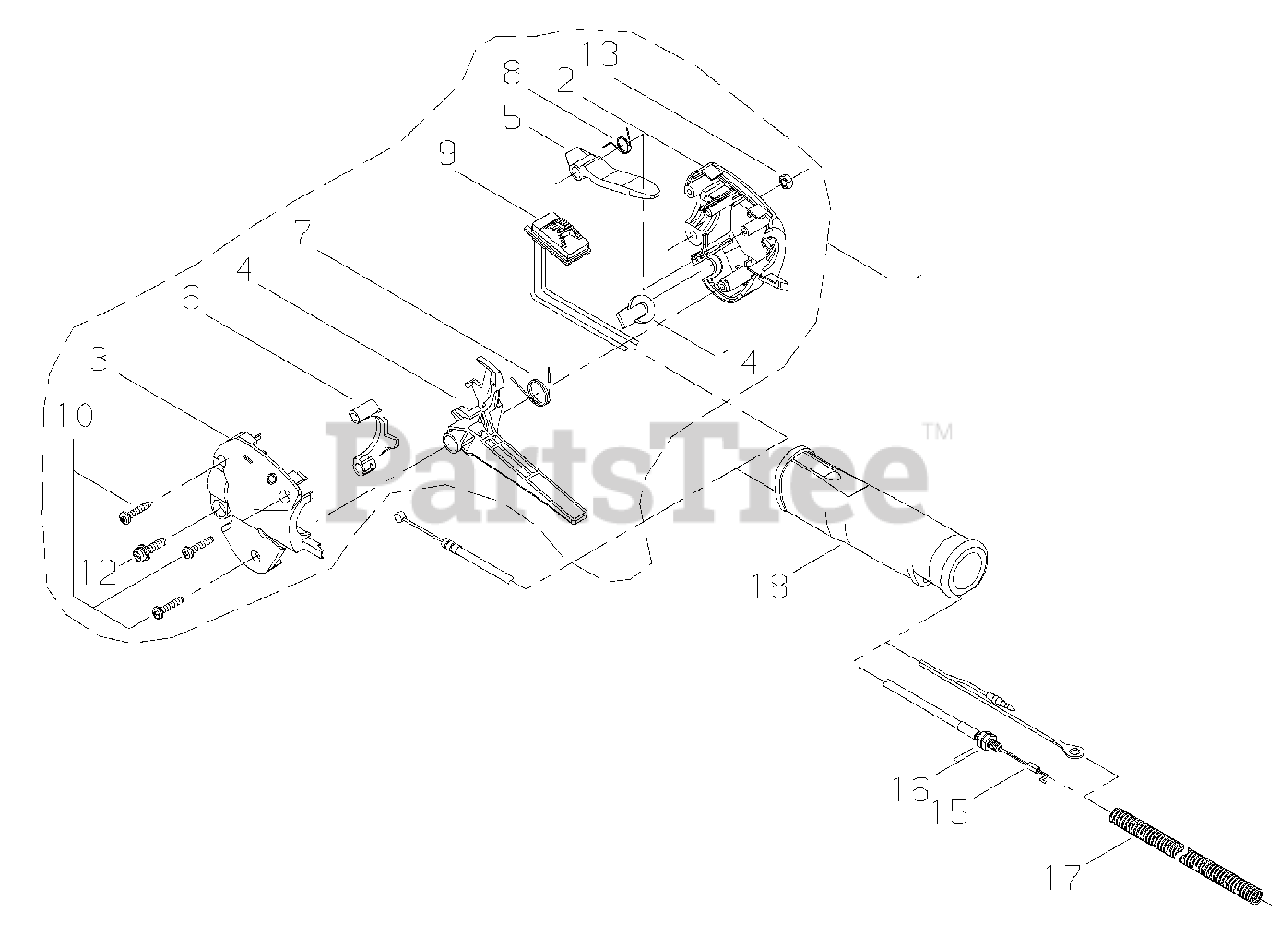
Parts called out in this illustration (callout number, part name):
2	HANDLE, CONTROL - RIGHT
3	HANDLE, CONTROL - LEFT
4	TRIGGER, THROTTLE
5	LEVER, TRIGGER LOCKOUT
6	LOCKOUT, THROTTLE
7	SPRING
8	SPRING
9	SWITCH
10	SCREW - 4X20 -- TAPPING
12	SCREW - 5X20
13	NUT - 5
14	PLUG
15	CABLE, THROTTLE
16	NUT - 6
17	TUBE
18	GRIP
